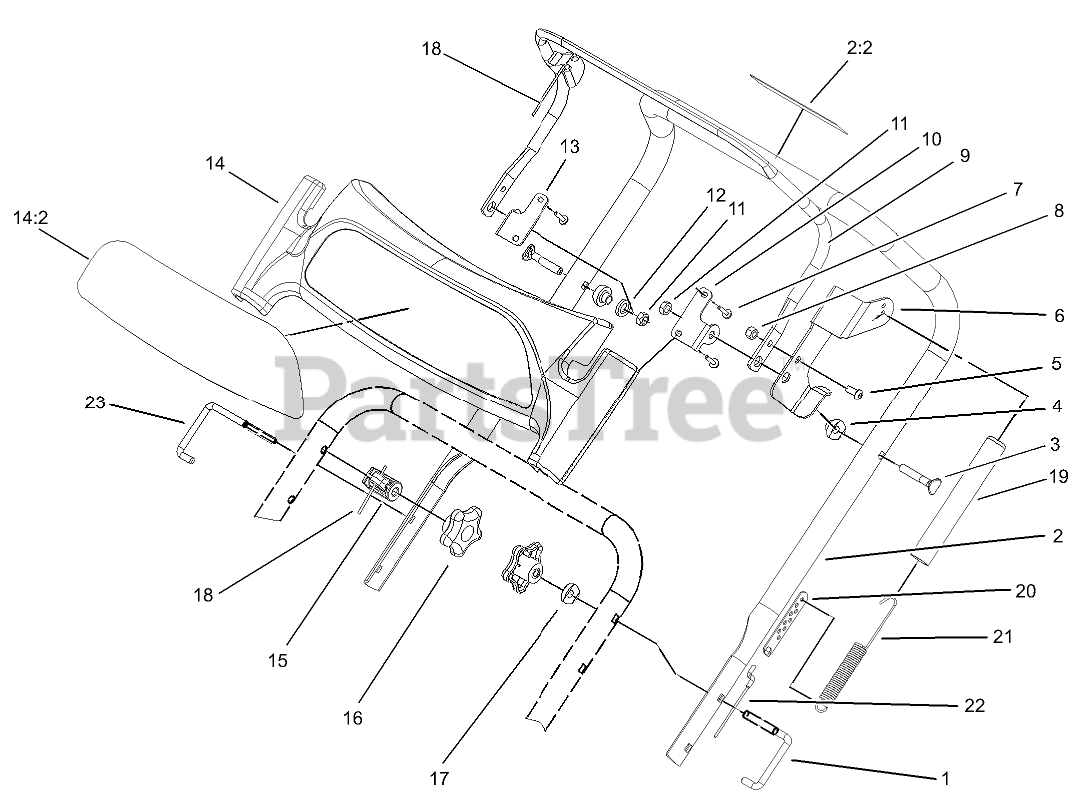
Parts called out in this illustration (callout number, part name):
1	LOCK-HANDLE
2	UPPER HANDLE ASM
2:2	DECAL-DRIVE, ROTOR
3	SCREW-HANDLE
4	SPACER-BAR, CONTROL
5	SCREW-HSBH
6	ARM-CLUTCH, HANDLE
7	SCREW-HWH
8	NUT-LOCK, NI
9	BAR-CONTROL
10	BRACKET-PANEL, LH
11	NUT-LOCK, NI
12	WASHER
13	BRACKET-PANEL, RH
14	DISPLAY HANDLE PANEL ASM
14:2	Decal-Display, Handle
15	GUIDE-Cable, PIVOT
16	KNOB-HANDLE
17	WASHER-CURVED
18	CABLE-PIVOT
19	COVER-SPRING
20	ADJUSTER-CABLE, CLUTCH
21	SPRING-CABLE
22	CABLE-CLUTCH
23	LOCK-HANDLE, RH
